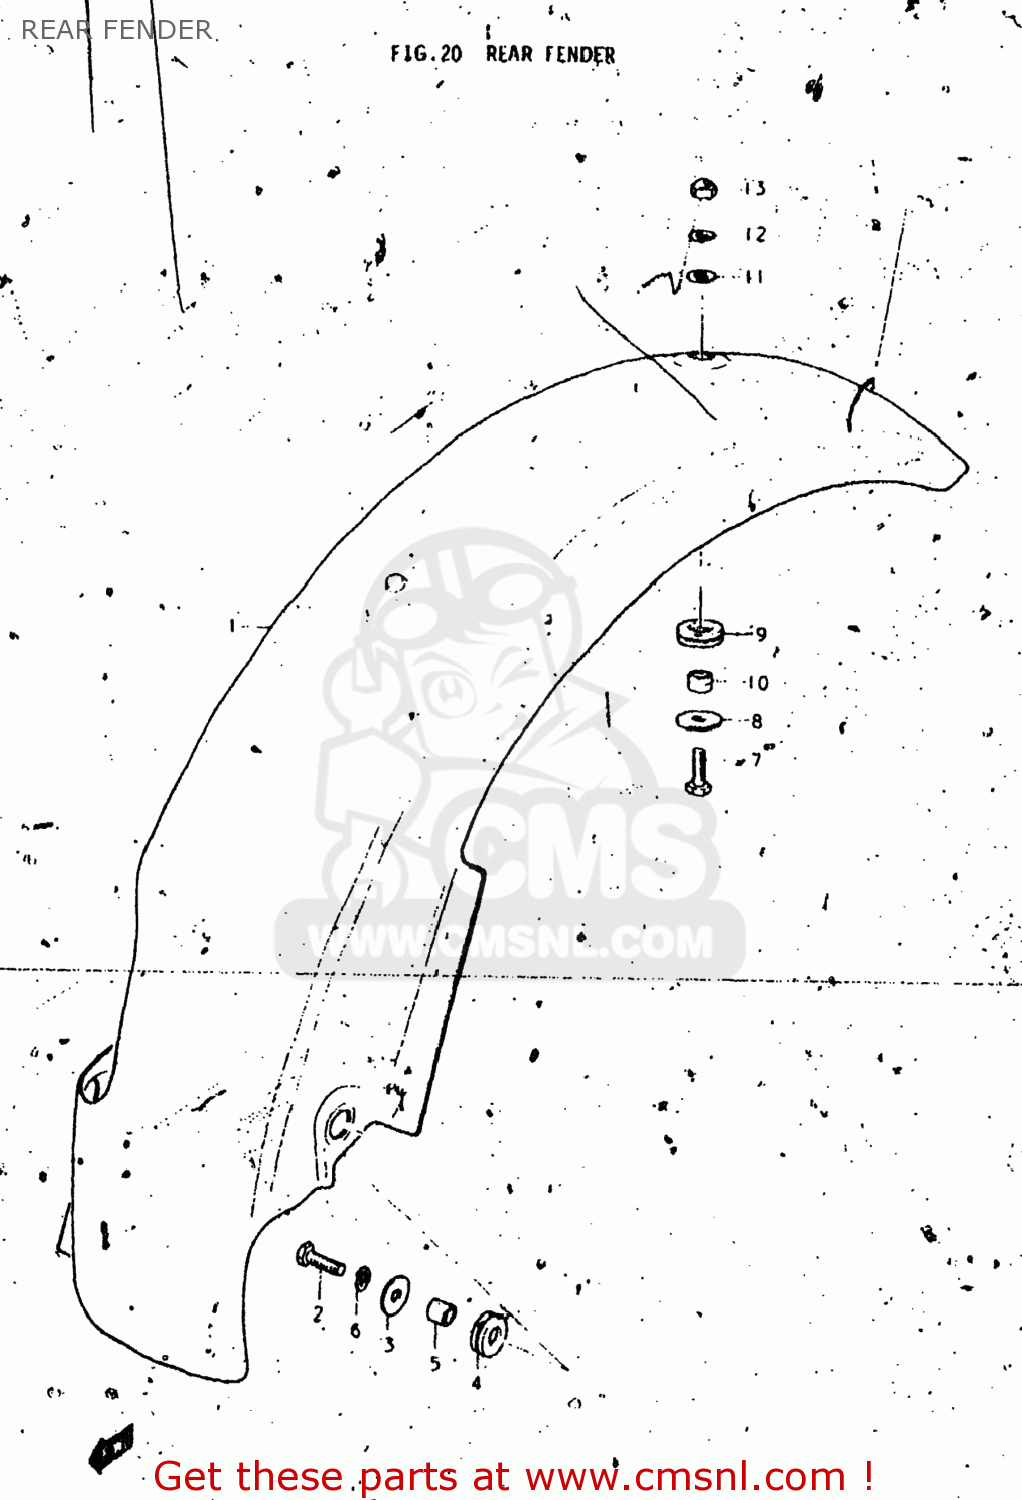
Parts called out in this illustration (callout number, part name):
1	FENDER,REAR
2	BOLT
3	WASHER (6.5X20X1.2)
4	CUSHION
5	SPACER(6.1X9X7.5)
6	LOCK WASHER
7	BOLT
8	WASHER (6.5X24X1.6)
9	CUSHION
10	SPACER
11	WASHER
12	LOCK WASHER
13	NUT
